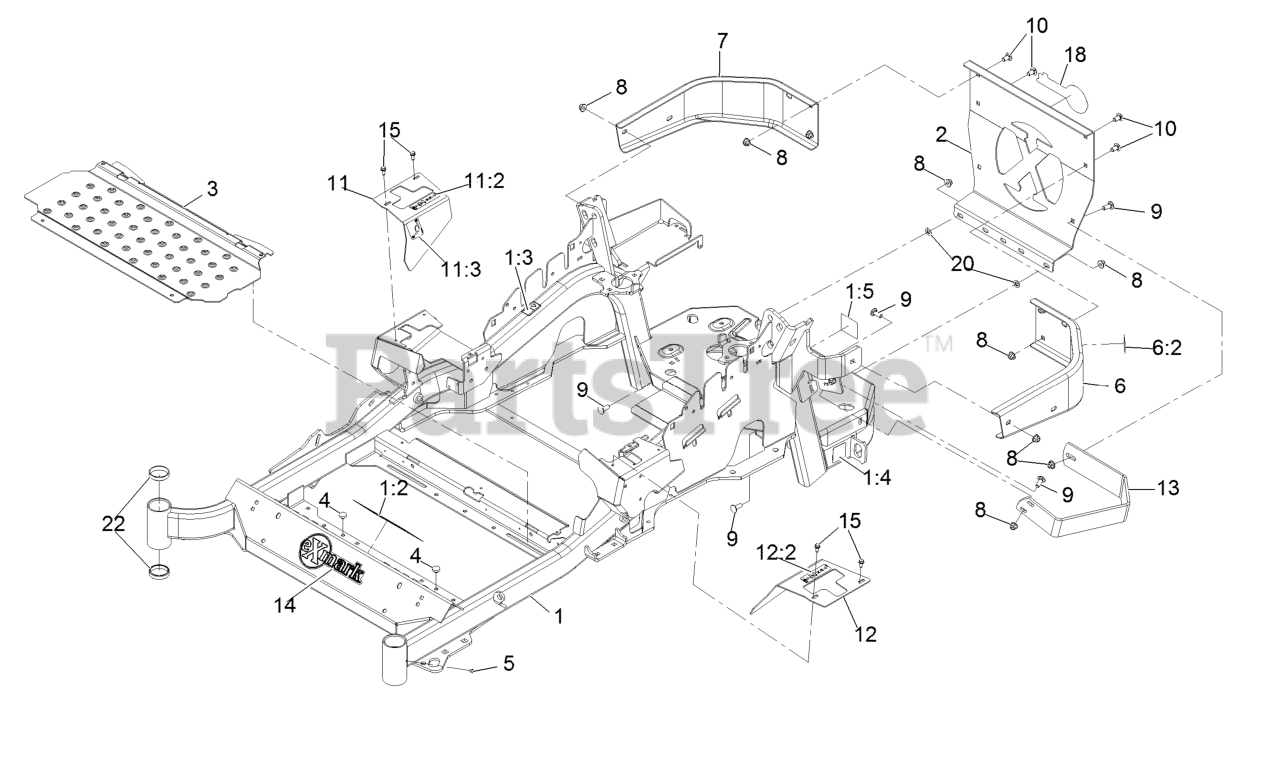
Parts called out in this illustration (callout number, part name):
1	Mainframe ASM
1:2	Decal-Danger
1:3	Decal-Warning
1:4	Decal-Hazard, Pinched Finger
1:5	Decal-Spark Arrester
2	Plate,Rear Guard
6	LH Bumper ASM
6:2	Decal-Warning
7	Bumper-RH
8	Nut-Nyloc 3/8-16 Flg
9	Bolt-Carriage 3/8-16 X 1
10	Bolt-Carriage 3/8-16 X 3/4
11	RH Motion Control Cover ASM
11:2	Decal-Control, Motion
11:3	Decal-Park Brake, CE
12	LH Motion Control Cover ASM
12:2	Decal-Control, Motion
13	Guard-Muffler
14	Decal-Exmark
15	Screw-HWH 1/4-20 X .62
18	Decal-Exmark Logo
20	Nut-Push 3/8-16
22	Cup-Bearing Tapered Roller
